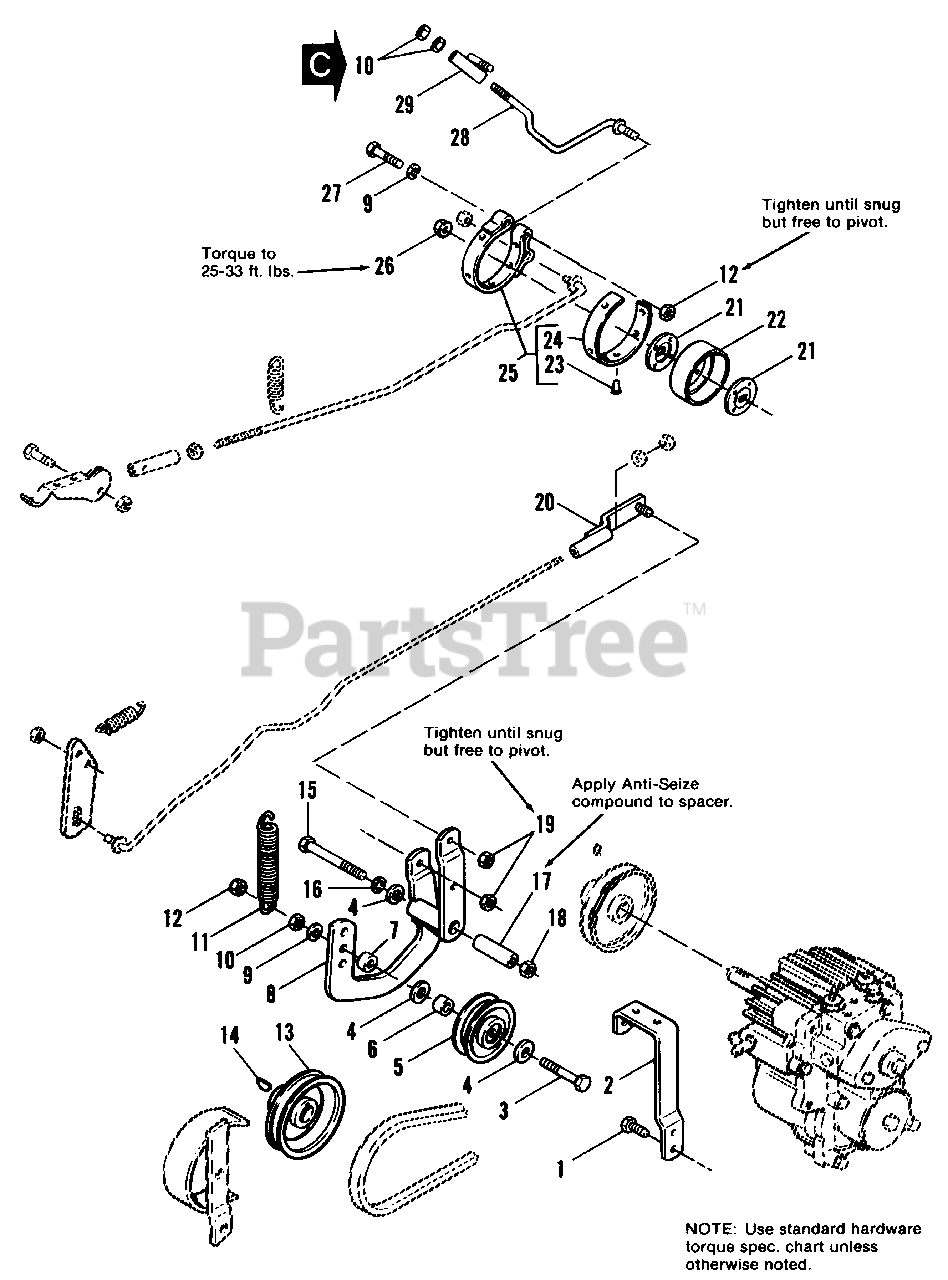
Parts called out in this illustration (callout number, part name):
1	SCREW, Thd. Form, 3/8 x 3/4
3	CAPSCREW, Hex Hd., 3/8-16 x 2-1/2
4	WASHER, 3/8
5	PULLEY ASSY.
8	LEVER ASSY., Idler
9	LOCKWASHER, 3/8
10	NUT, Hex, Full, 3/8-16
12	LOCKNUT, Hex, 3/8-16
13	PULLEY
14	KEY
15	CAPSCREW, Hex Hd., 7/16-14 x 3-3/4
16	LOCKWASHER, 7/16
18	NUT, Hex, Full, 7/16-14
19	LOCKNUT, Hex, 5/16-18
20	GUIDE ASSY.
21	WASHER, Special
22	DRUM, Brake
24	LINING, Brake
25	BAND ASSY., Brake
26	LOCKNUT, Flange, Whiz, 7/16-14
27	CAPSCREW, Hex Hd., 3/8-16 x 1-3/4
29	GUIDE ASSY., Rod
